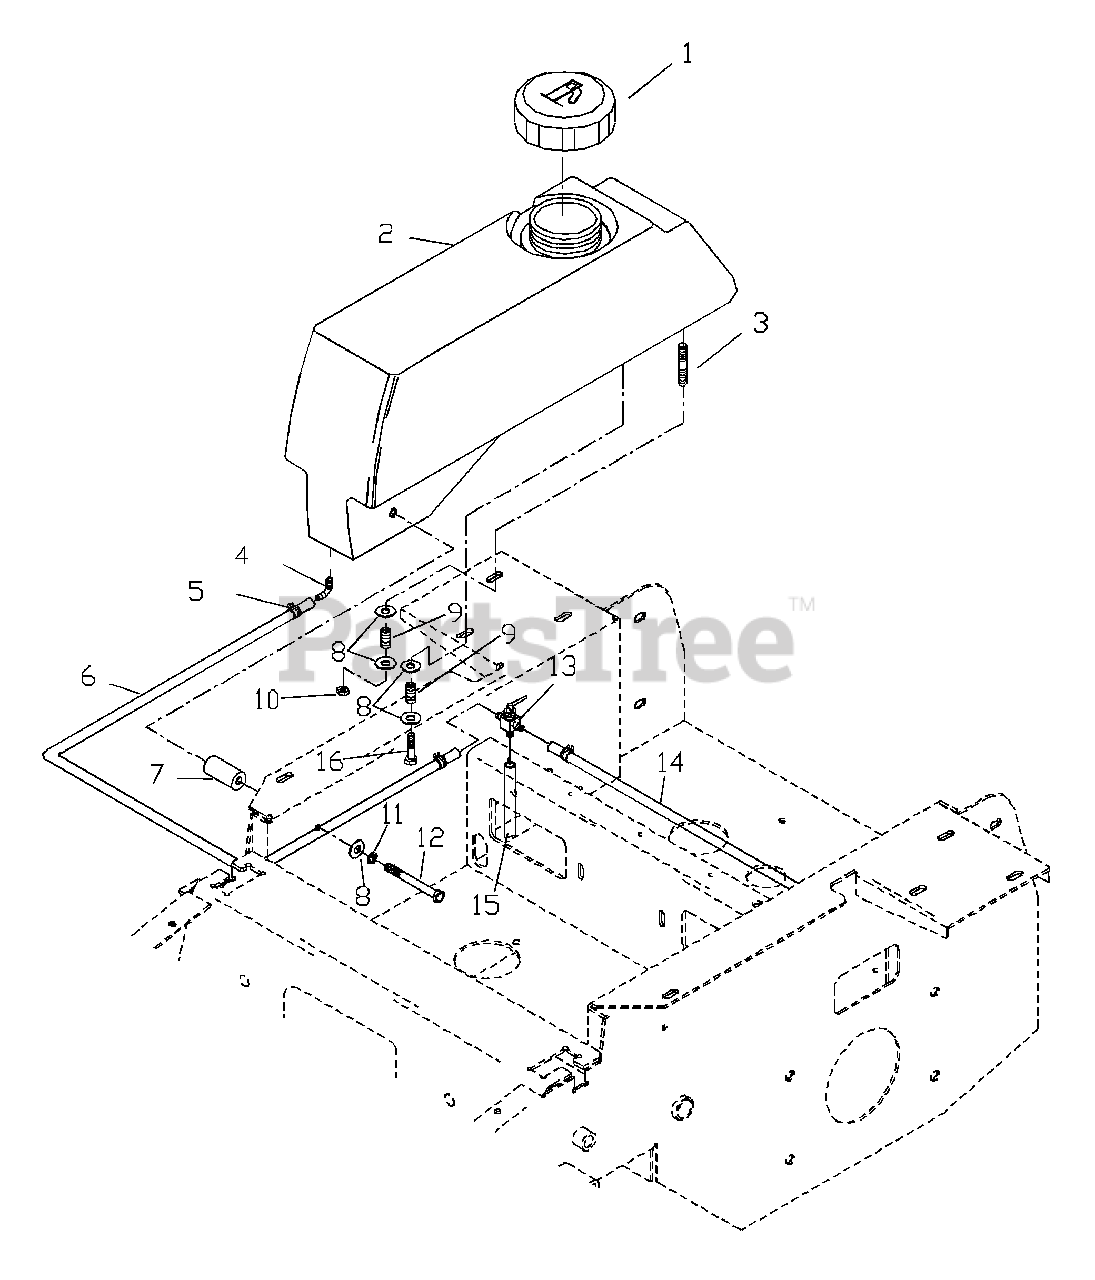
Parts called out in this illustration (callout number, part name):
1	FUEL CAP
2	RT. FUEL TANK
2	LT. FUEL TANK
4	90 DEG. HOSE BARB
5	HOSE CLAMP
6	FUEL LINE 30" (2 ON KAW.)
7	TANK SPACER
8	5/16 FLAT WASHER
10	5/16C LOCKNUT
11	5/16 LOCK WASHER
12	HCS 5/16C X 4
13	FUEL VALVE
14	FUEL LINE 41"
15	FUEL LINE 16" (KOHLER)
16	HCS 5/16C X 1
